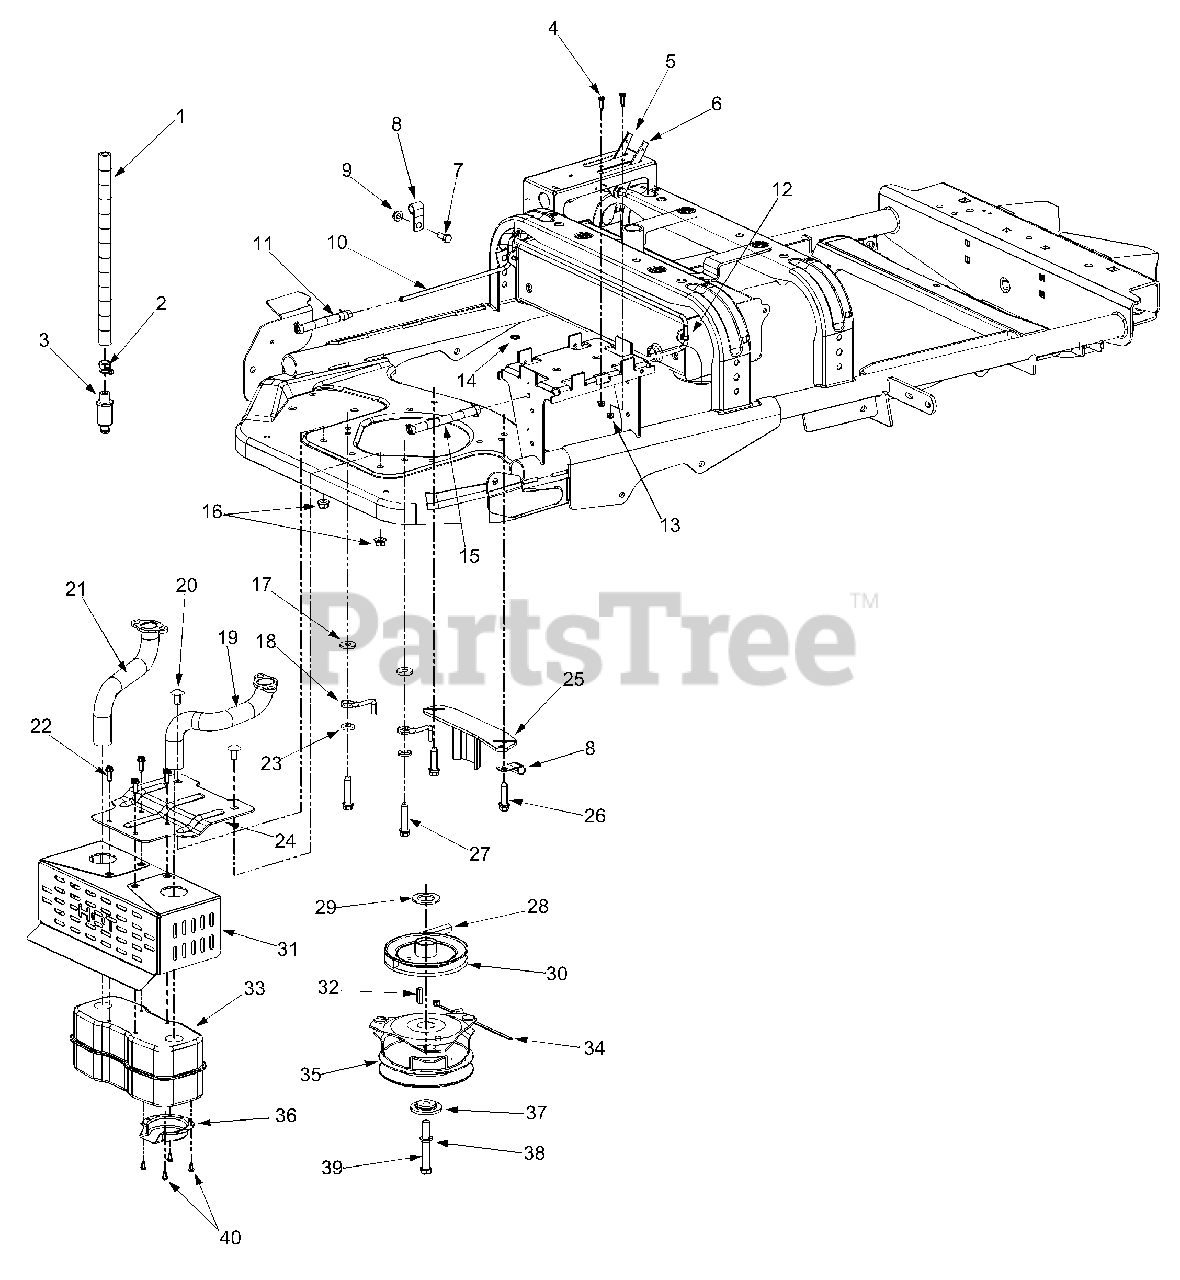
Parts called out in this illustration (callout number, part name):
1	Oil Drain Hose
2	Oil Drain Cap
3	Oil Drain
4	Screw #10-24 x .750
5	Throttle Control Cable 40.5"
6	Choke Control Cable 38.0"
7	Hex Cap Screw 5/16-18 x .75
8	Cable Clip Heat Shield
9	Hex Lock Nut 5/16-18
10	Fuel Line
11	Hose Clamp
12	Retainer Clip
13	Lock Nut #10-24
14	Lock Washer 5/16
15	Fuel Line Hose
16	Flange Lock Nut 3/8-16
17	Flat Washer .385 ID x 1.0 OD
18	Rear Belt Retainer Rod
19	Exhaust Pipe LH
20	Carriage Bolt 3/8-16 x .75
21	Exhaust Pipe RH
22	Hex Washer Screw 1/4-20 x .75
23	Flat Washer .407 ID x .812 OD
24	Muffler Bracket
27	Hex Washer Screw 3/8-16 x 1.875
28	V-Belt
29	Flat Washer 1.0 ID x 1.75 OD
30	Drive Pulley
33	Duel Muffler
34	Cable Tie
35	Electric PTO Clutch
36	Muffler Deflector
37	Spacer Clutch
38	Lock Washer 7/16
39	Hex Cap Screw 7/16-20 x 3.25
40	Hex Washer Screw #8-32 x .375
